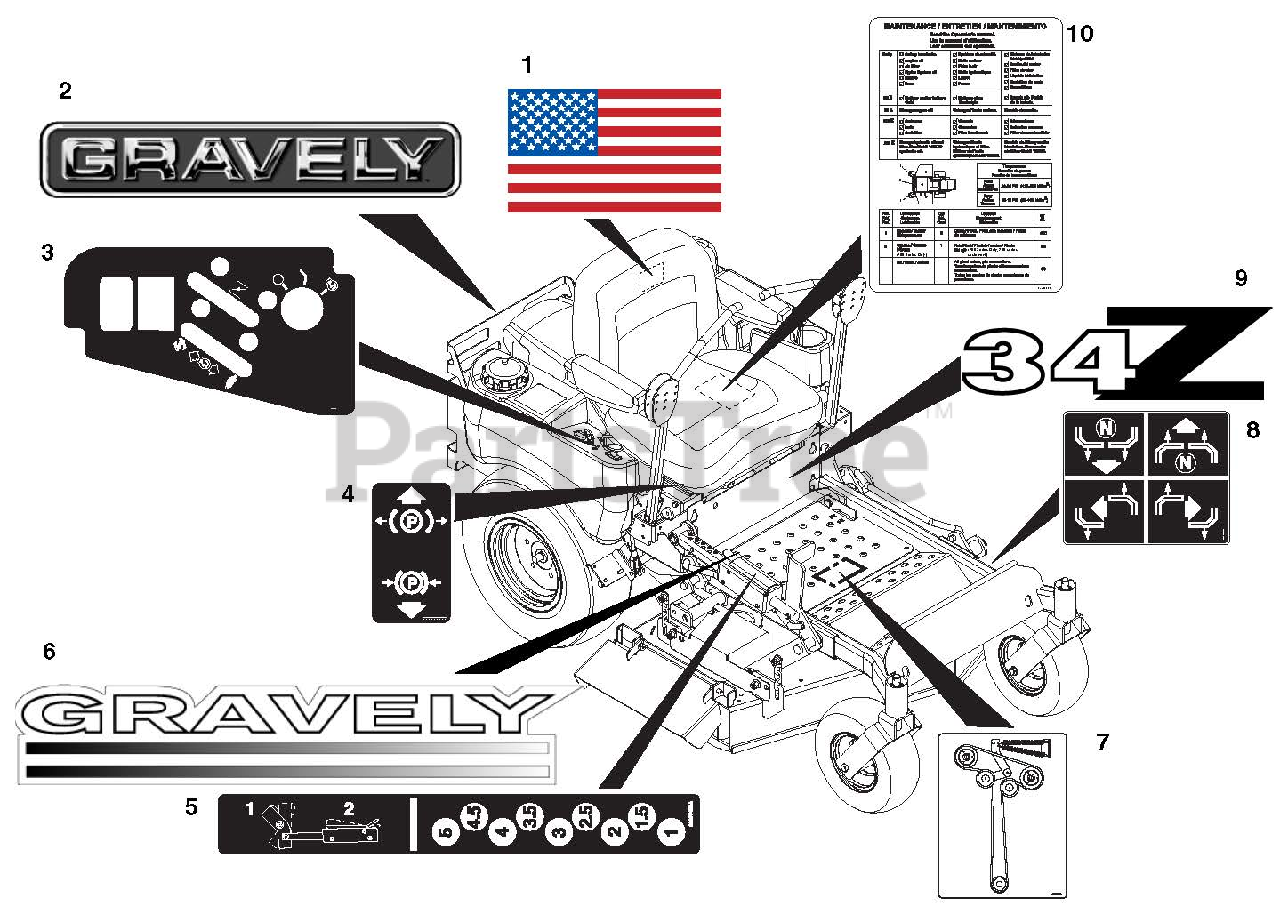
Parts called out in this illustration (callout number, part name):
1	Decal, American Flag
2	Decal, 15" Gravely Logo
3	Decal, Control Panel
4	Decal, Parking Brake Lever
5	Decal, Height of Cut
6	Decal, ZT Hood
7	Decal, Belt Diagram
8	Decal, Instructional Steering
9	Decal, PM 34Z
9	Decal, PM 44Z
10	Decal, Maintenance Instructions
